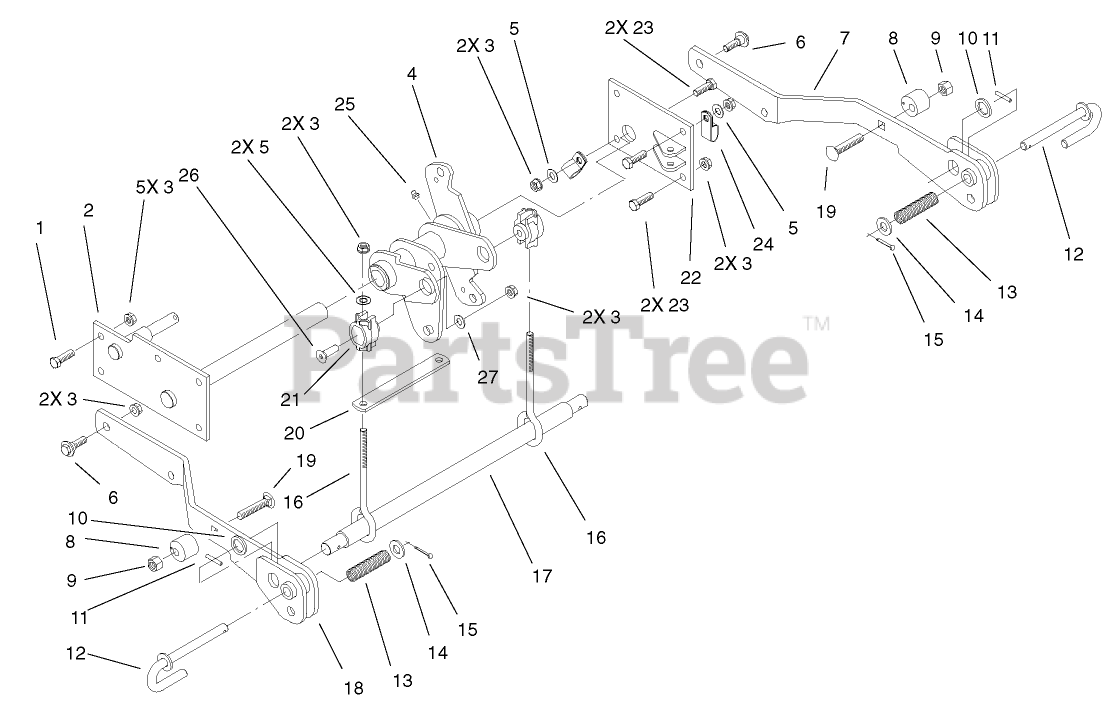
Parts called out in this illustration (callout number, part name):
1	SCREW-HH
2	SUPPORT-LIFT, DECK
3	NUT-LOCK, NI
4	BELLCRANK AND BUSHING ASM
5	WASHER-FLAT
6	SCREW-SHOULDER, HWH
7	ARM-LIFT, LH
8	STOP-LIFT, ADJ.
9	NUT-LOCK, NI
10	WASHER-FLAT
11	PIN-ROLL
12	PIN - J
13	SPRING-COMPRESSION
14	WASHER-FLAT
15	PIN-COTTER
16	ROD-LIFT
17	BAR-LIFT
18	ARM-LIFT, RH
19	SCREW-CARR
21	SLEEVE-LIFT
22	SUPPORT-CYLINDER
23	SCREW-HH
24	CLAMP-TUBE
25	FITTING-GREASE
26	SCREW-HSFH
27	WASHER-FLAT
